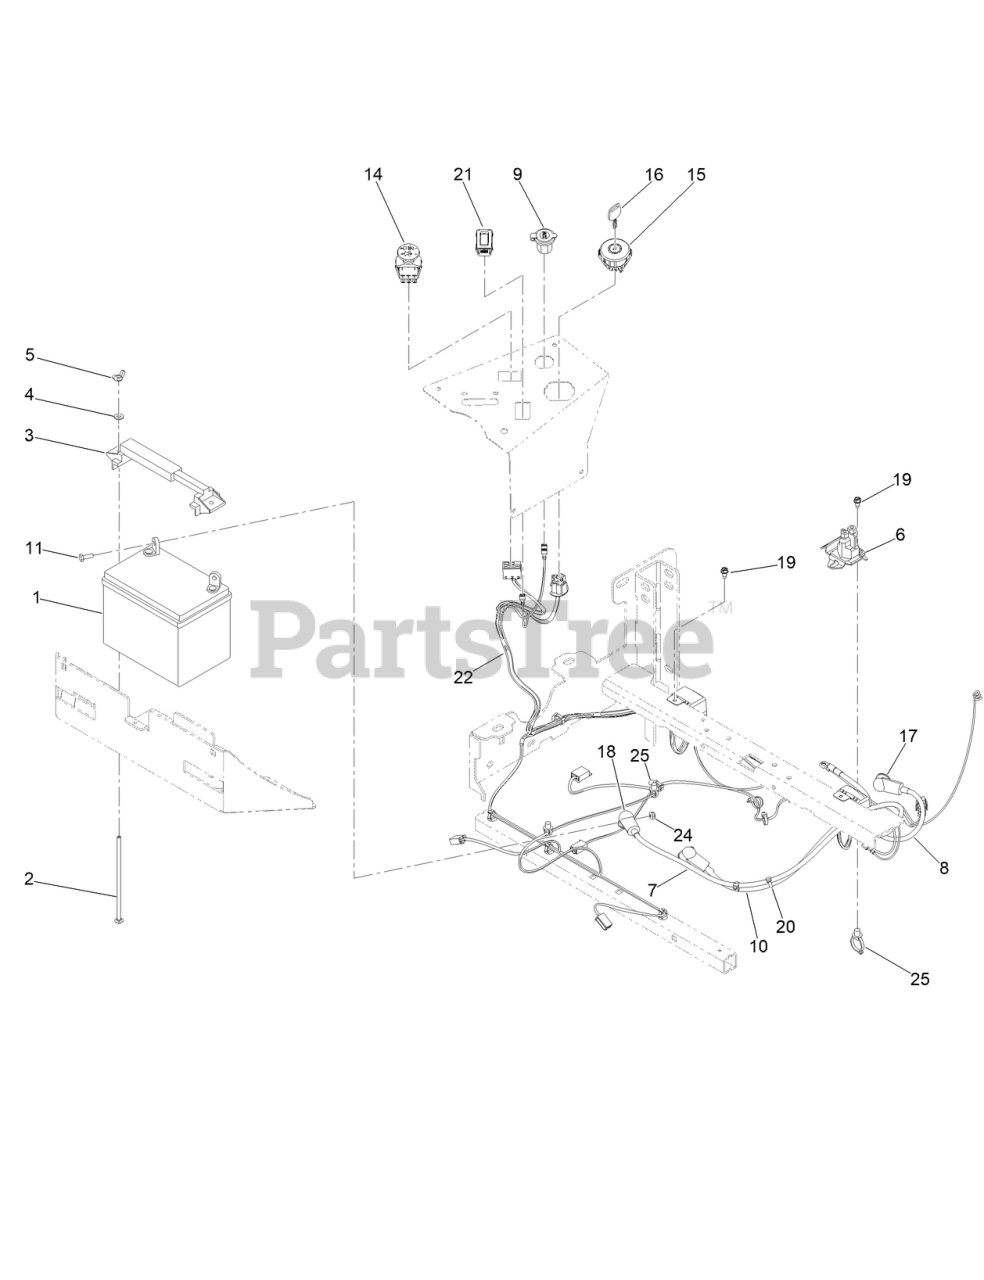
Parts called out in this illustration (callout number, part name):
1	12 VOLT START BATTERY 300CCA
2	1/4-20 X 7 CARRIAGE BOLT ZINC
3	BATTERY HOLD DOWN
4	WASHER-FLAT
5	NUT-WING
6	HEAVY DUTY START SOLENOID
7	MWR NEGATIVE CABLE 28
8	MWR START WIRE 12
9	12 VOLT AUXILLIARY PLUG
10	MWR POSITIVE BATTERY CABLE 25IN
11	SCREW-HH
14	PTO SWITCH
15	IGNITION SWITCH
16	2023 MWR KEY
17	3.15 LGTH STRAIGHT INSUL TERM COVER RED
18	STRAIGHT INSULATING TERMINAL COVER
19	SCREW-HWH
20	TIE-CABLE
21	HOUR METER
22	HARNESS-WIRE
24	NUT-HF
25	CLIP-TIE
